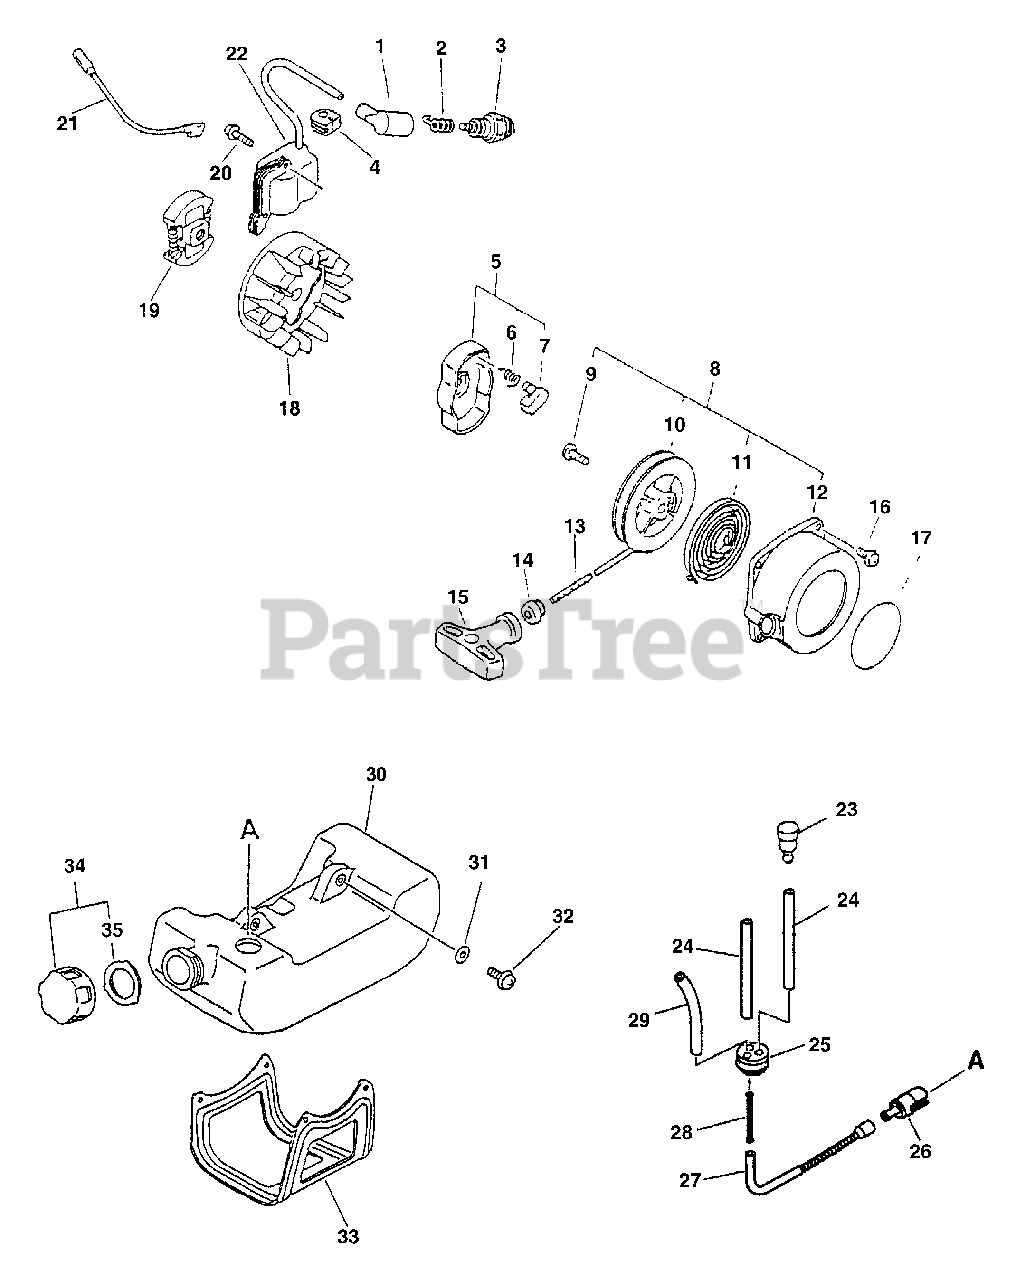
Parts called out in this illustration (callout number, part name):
1	CAP, SPARK PLUG
2	TERMINAL, SPARK PLUG CAP
3	SPARK PLUG -- BPM-7Y
3	SPARK PLUG -- BPMR-7A
5	STARTER PAWL ASSY
6	SPRING, RETURN
7	PAWL, STARTER - BLACK
8	STARTER ASSY
10	REEL, ROPE
11	SPRING, REWIND
12	CASE, STARTER
13	ROPE, STARTER - 3X890
14	GUIDE, ROPE
15	GRIP, STARTER
16	SCREW - 4X16
17	LABEL - ECHO
18	FLYWHEEL
19	CLUTCH ASSY
20	SCREW - 4X22
21	LEAD - IGNITION
22	COIL, IGNITION
23	VENT, FUEL TANK
24	PIPE - 3X5X70 -- BLACK
25	GROMMET
26	FILTER, FUEL
27	PIPE, FUEL - CORRUGATED
28	CONNECTOR, PIPE
29	PIPE - 3X6X90 -- CLEAR
30	FUEL TANK ASSY
31	WASHER - 5
32	SCREW - 5X16
33	GUARD, FUEL TANK
34	CAP ASSY
35	GASKET, CAP
